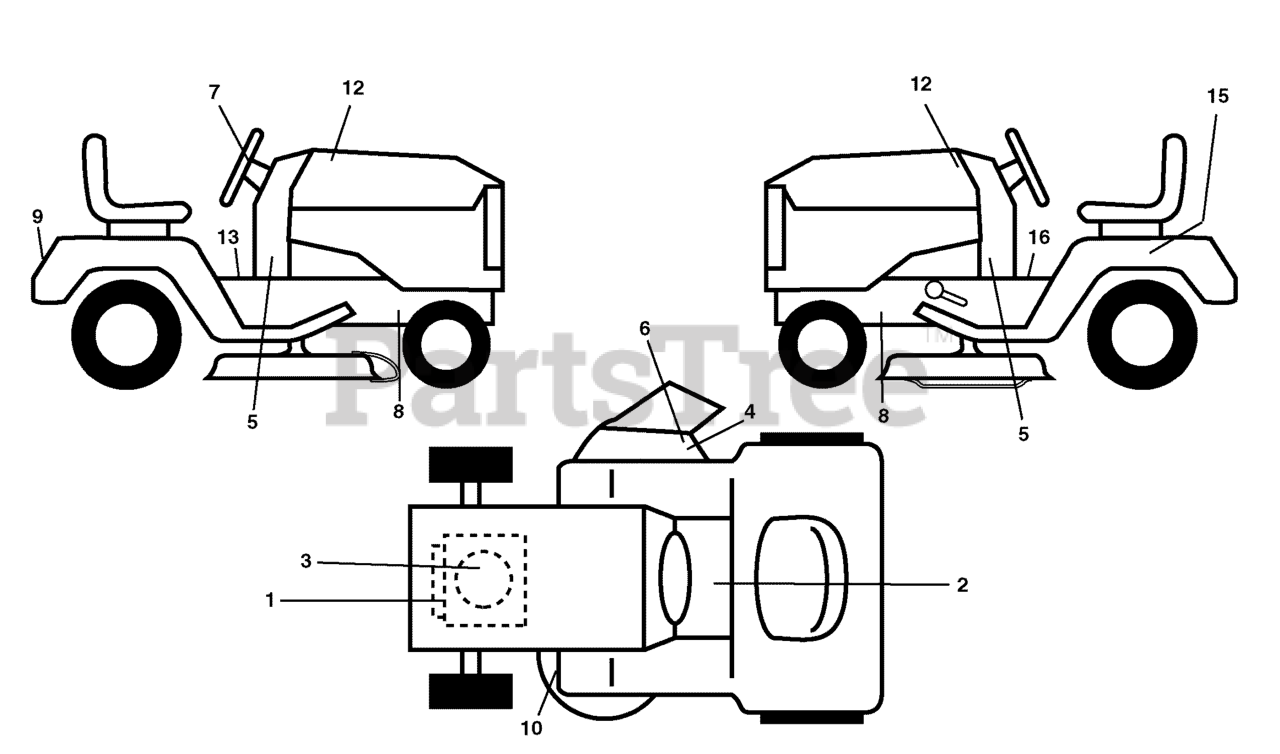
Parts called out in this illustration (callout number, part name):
1	DECAL, Warning, Eng. Sym.
2	DECAL, Warning Symbols
3	DECAL, Engine, HP
4	DECAL, Warning
5	DECAL, Lower Dash
6	DECAL, Cutfinger CE
7	DECAL, Ins Str Wh
8	DECAL, Chassis Hot
9	DECAL, Fender
10	DECAL, V-bolt Sch.
12	DECAL, Hood, LH/RH Set
13	DECAL, Brake / Clutch Symbol
15	DECAL, Caution, Battery
16	DECAL, Saddle Brake Parking
